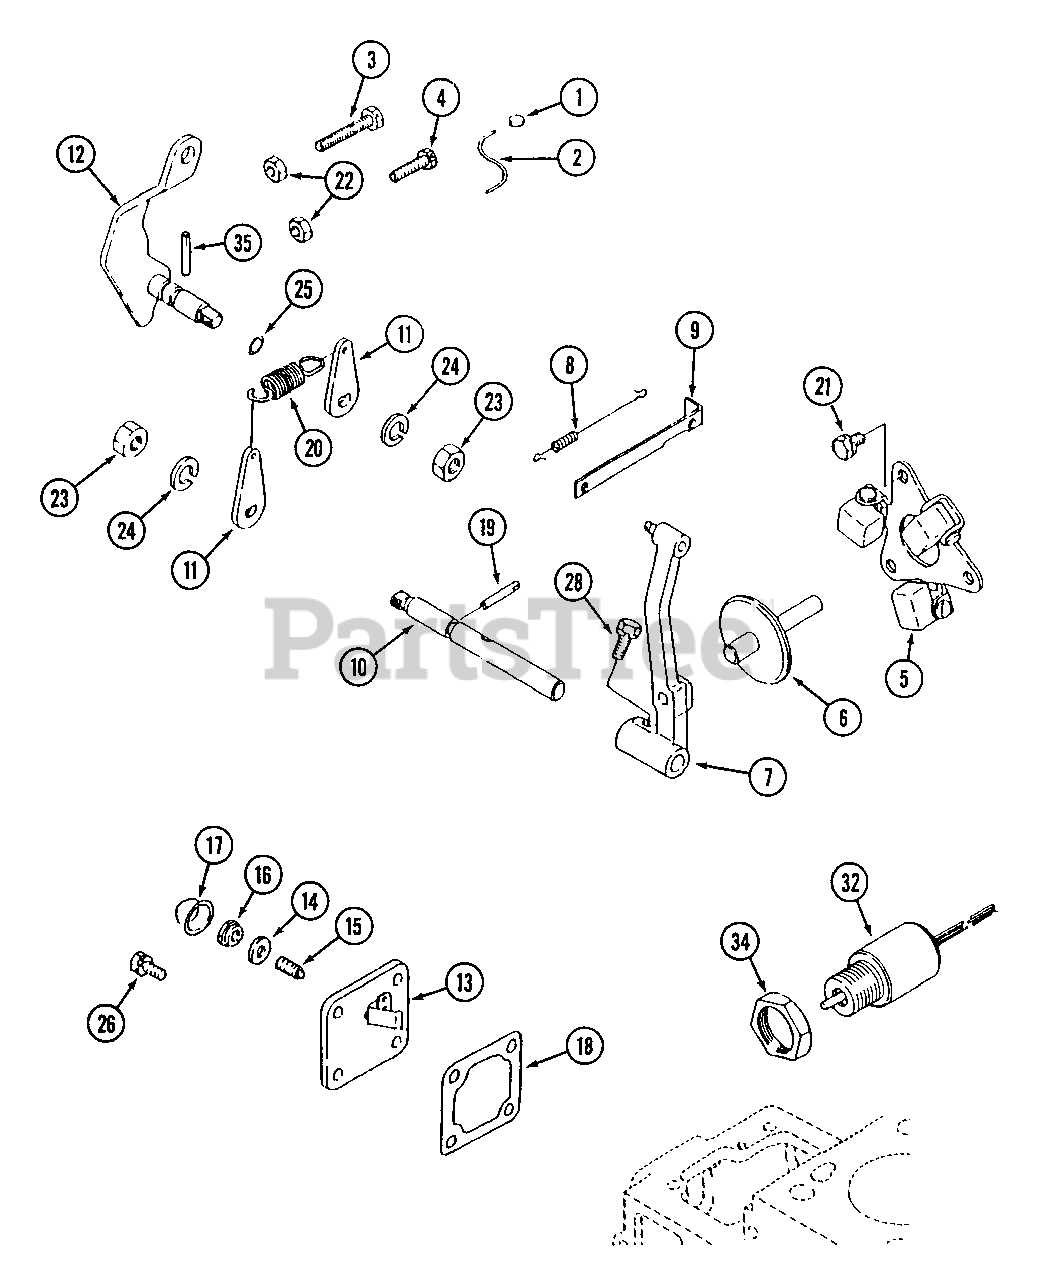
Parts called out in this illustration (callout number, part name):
1	Metal, Sealing
3	Bolt, High Speed Set
4	Bolt, Low Idle Set
5	Governor Weight Ass'y.
6	Sliding Shaft Ass'y.
7	Governor Lever Ass'y.
8	Spring, Tie Rod
9	Rod, Tie
10	Shaft, Governor
11	Lever, Governor Spring
12	Speed Control Lever Ass'y.
13	Tie Rod Cover Ass'y.
15	Screw, Adjusting
16	Nut, Special
17	Cap, Sealing
18	Gasket, Cover
19	Pin, Grooved
20	Spring, Governor
21	Bolt, w/Washer
24	Washer, Spring
26	Bolt, w/Washer
28	Bolt, w/Washer
32	Solenoid & Nut Set
35	Pin, Grooved
